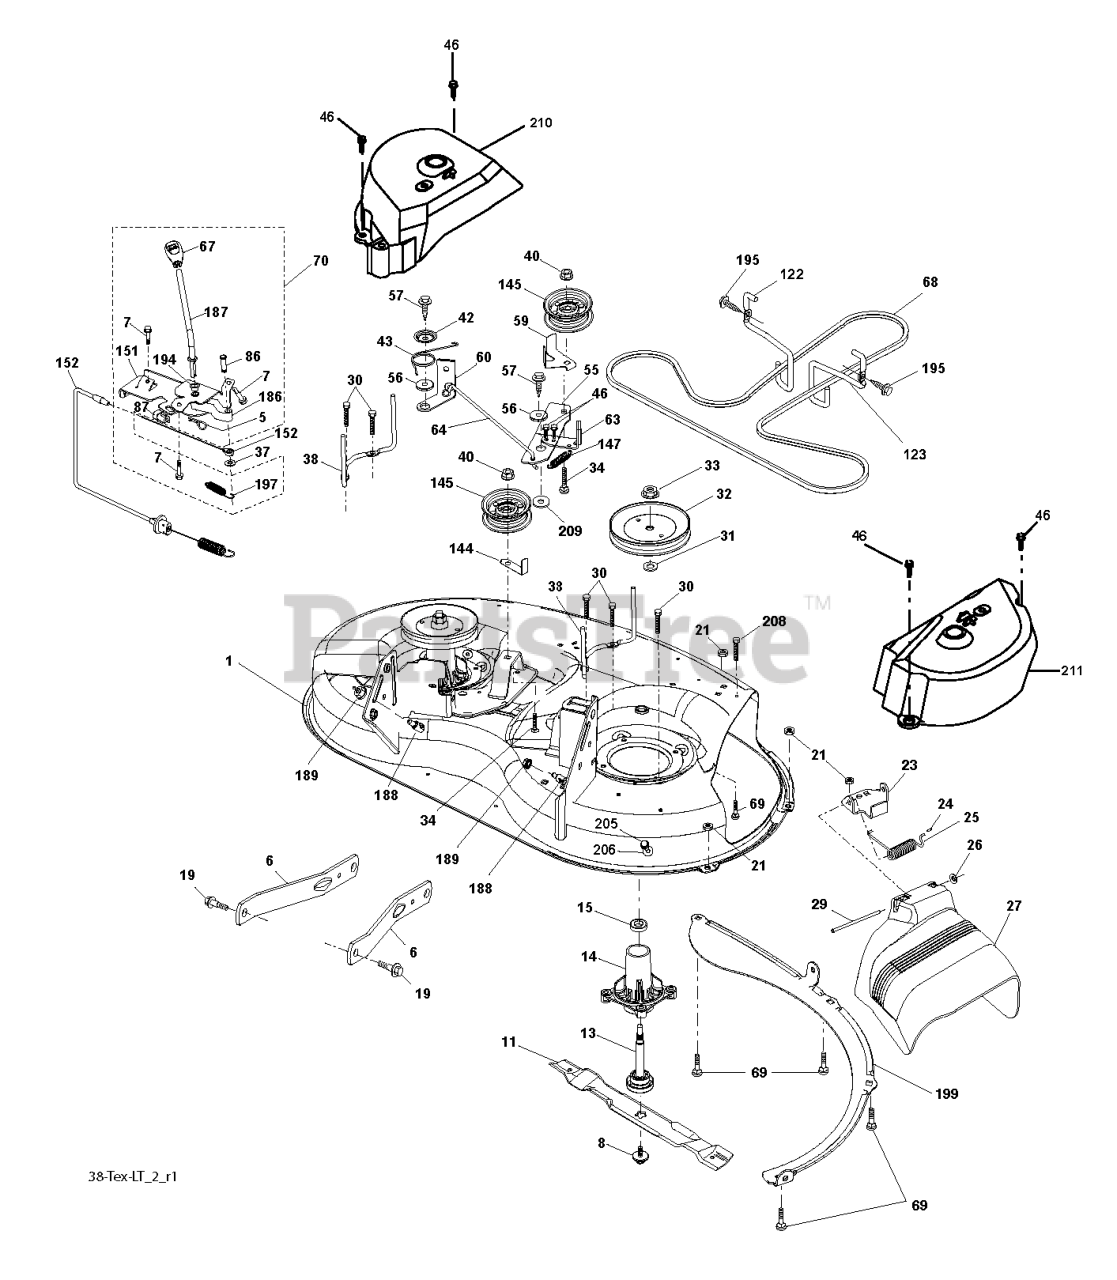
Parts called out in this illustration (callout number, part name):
1	HOUSING
5	RETAINER-SPRNG RB
6	ARM.SUSPENSION.MOWER.R
7	SCREW
8	BOLT.WASHER.ASM.7/16-2
11	BLADE 38" PREMIUM
13	SHAFT.ASM.MDRL.N/GREASE.38
14	RP.HOUSING.MANDREL.4PT.
19	BOLT.SHOULDER
21	LOCKNUT
23	BRKT.DEFLECTOR.38"2005+
24	CAP-SLEEVE LT
25	SPRING.TORSION.DEFLECT
26	NUT PUSH M
27	SHIELD ASM.DFLCTR MWR.38-7"BLK
29	ROD.HINGE
30	SCREW, WASHER HEAD
31	WASHER.SPACER.MANDREL
32	PULLEY.MANDREL.5.0.PD.38"
33	NUT.FLANGE.LOCK.TOP
34	BOLT.3/8-16X1.50
37	WASHER
38	KEEPER BELT LH MANDREL
40	NUT LOCK FLG 3/8-16 UNC
42	SPRING.TORSION.BRAKE
43	SRPING.TORSION.RETAINE
46	SCREW.1/4-20X5/8
56	SPACER.RETAINER
57	SCREW 3/8-16X1
59	GUARD, BELT
60	ARM BRAKE MOWER RH 38"
63	RP ARM.BRAKE.MOWER.38"LH.TEX
64	LINK BRAKE
67	HANDLE.CLUTCH.CABLE.LT
69	BOLT
70	CLUTCH.ASM.MANUAL.LT.PRED
86	PIN ATTACHMENT CABLE
87	SWITCH.INTRLCK.CLUTCH.
122	KEEPER BELT ENGINE LH
123	KEEPER BELT RH
144	KEEPER BELT
145	PULLEY.IDLER.48"PRIMARY
147	SPRING RETURN
151	BRACKET.CLUTCH CBL.PRED LT
152	CLUTCH CABLE
186	ARM ACTUATOR
187	LEVER.CONTROL.CL.CABLE.PRED LT
188	STUD.FASTNER.W/ANTI-ROTATE
189	NUT LOCK HEX FLANGE 5/16-18
194	BEARING.CONTROL.LEVER.CLUTCH
195	SCREW, 3/8-16X3/4
197	SPRING.PLUNGER.ACTUATOR
199	BAFFLE.VORTEX.FRONT.38"
205	SCREW
208	SCREW 3/8-16X1/2
209	WASHER 12/32X2X10GA
